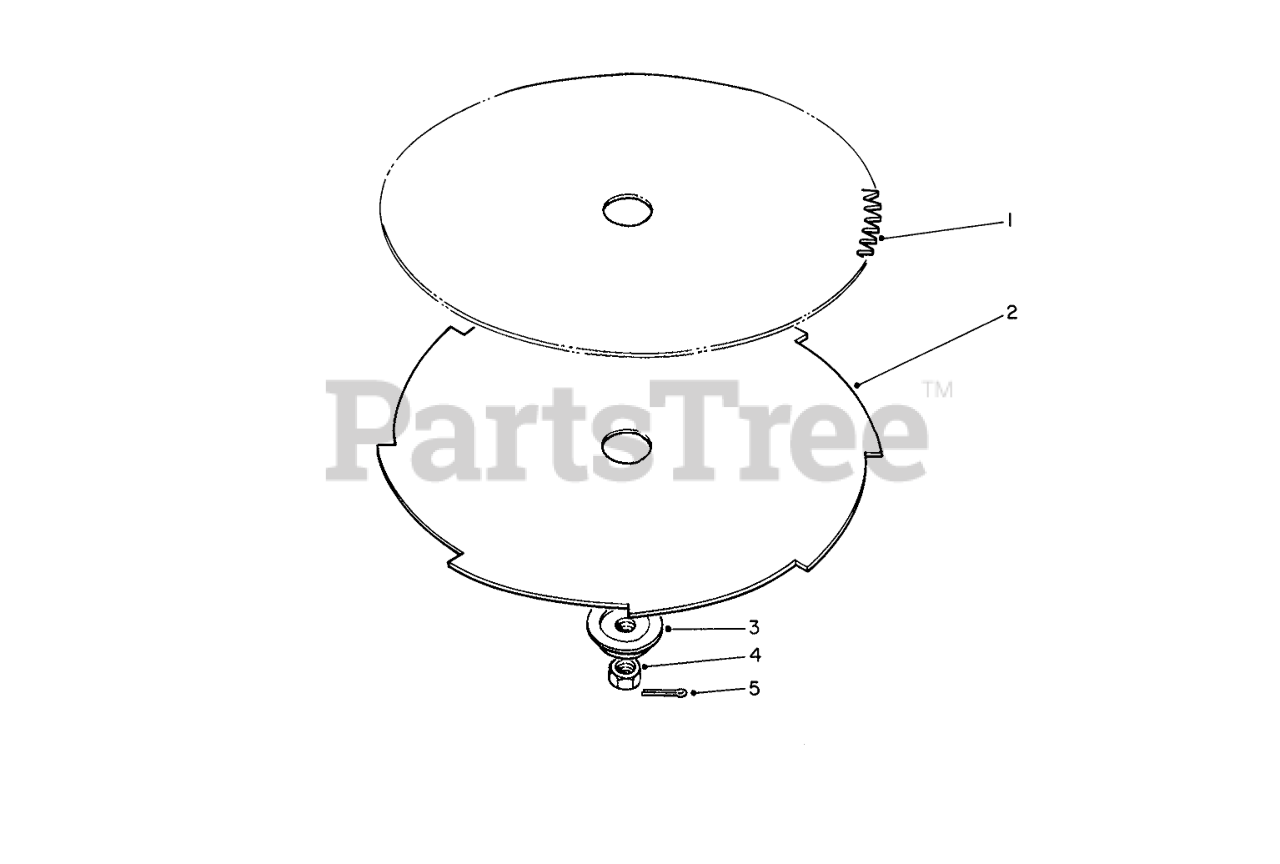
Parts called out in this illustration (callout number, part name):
1	SAW BLD PKG(8", 80T)
2	BRUSH BLD PKG(8",8T)
3	Adapter-Blade
5	1/16 X 1 LG COTTER PIN
